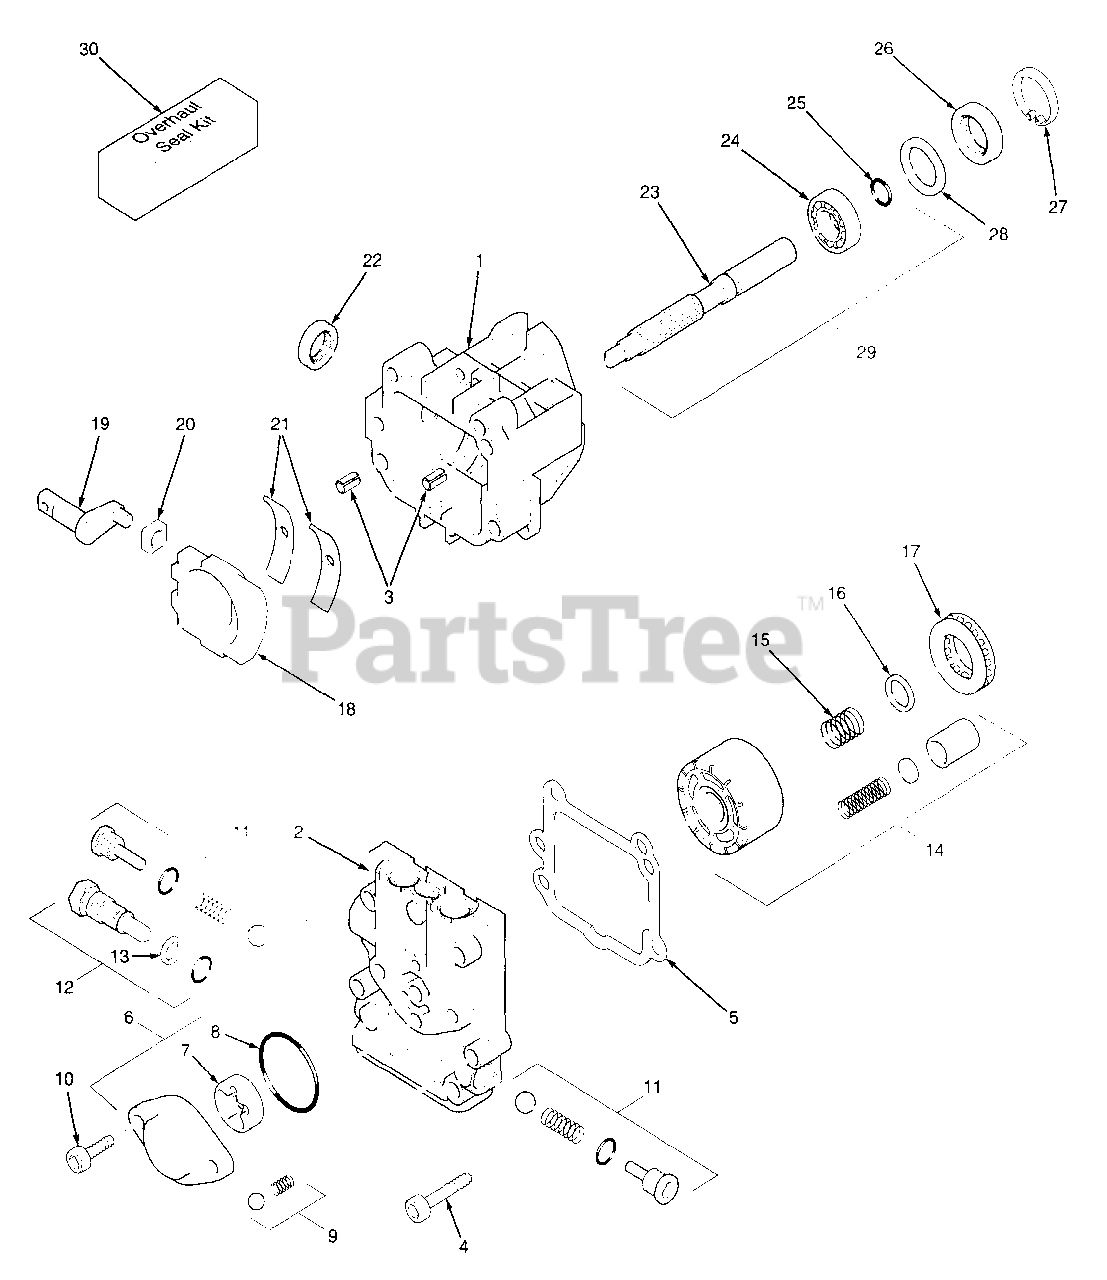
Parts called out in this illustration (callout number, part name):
1	Housing Kit
2	End Cap
3	Straight Headless Pin
4	Socket Head Screw
5	End Cap Gasket
6	Charge Pump Kit
7	Gerotor Assembly
9	Charge Relief Valve Kit
10	Socket Head Screw
11	Check Valve Kit
12	Bypass Valve Kit
13	Backup Ring
14	Cylinder Block Kit
15	Block Spring
16	Block Thrust Washer
17	Roller Thrust Bearing
18	Swash Plate
19	Trunnion Arm
20	Guide Slot
21	Cradle Bearing
23	Pump Shaft
24	Ball Bearing
25	Retaining Ring
27	Retaining Ring
28	Spacer
29	Shaft Kit
30	Overhaul Seal Kit
